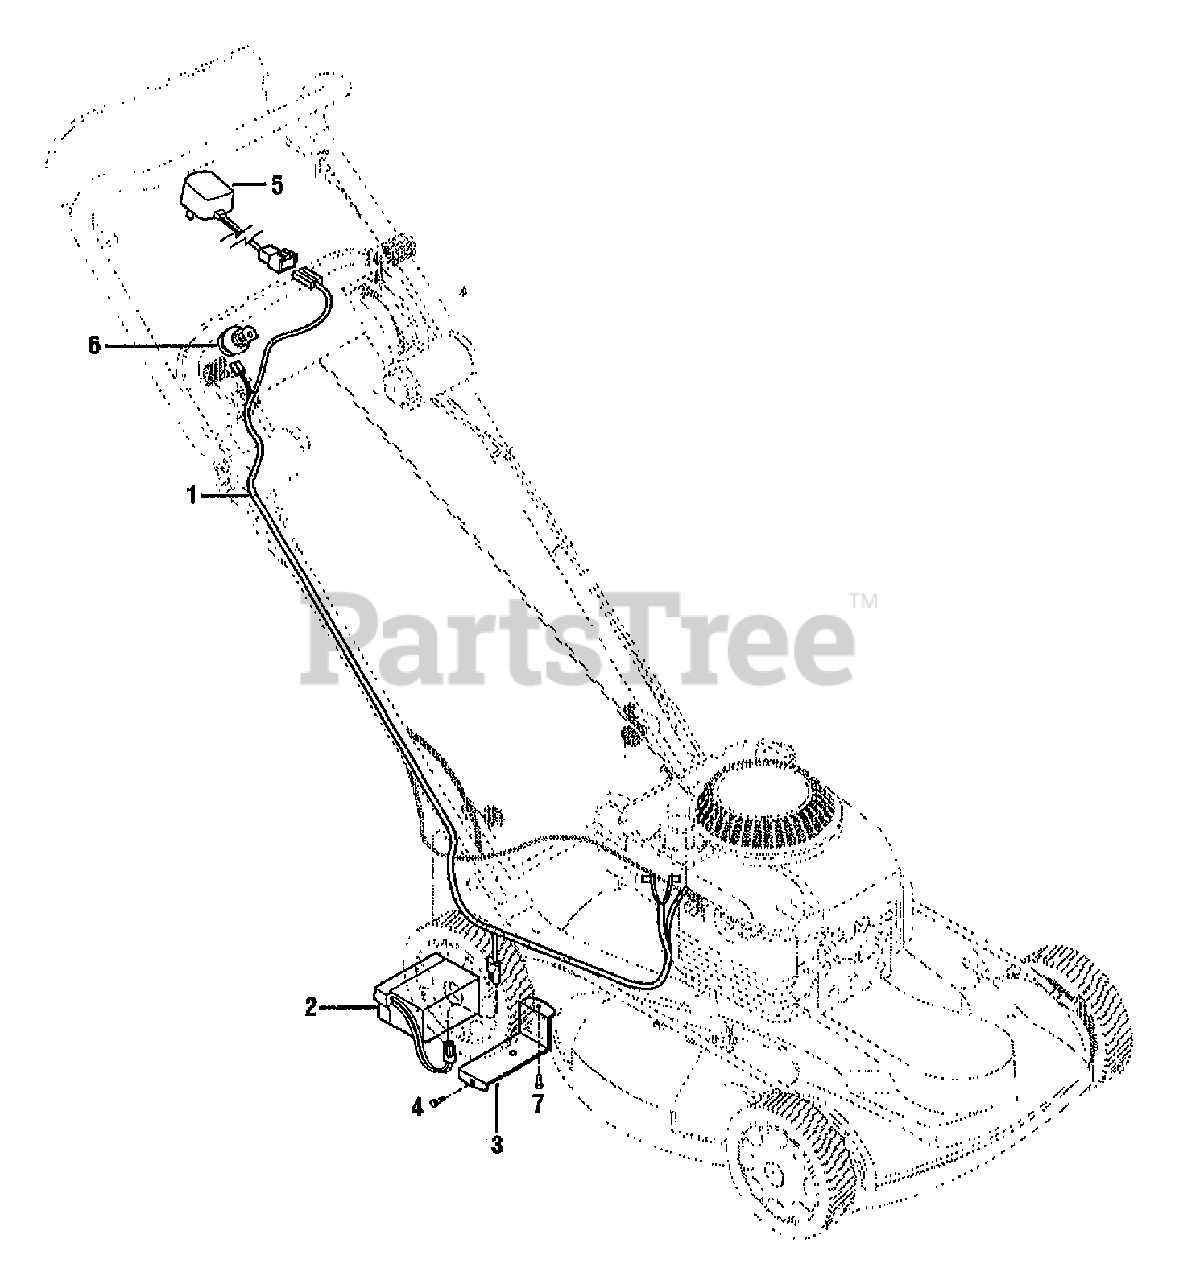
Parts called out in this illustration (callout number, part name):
1	HARNESS-WIRE
2	KIT-BATTERY REPLACE
3	BRKT-BATTERY PAINTED
4	SCR-FLANGE 1/4-20X3/4 GR5
5	CHARGER-BATTERY
6	SEE GRID C-3
7	SCR-HWH 1/4-20 X .5 STH
